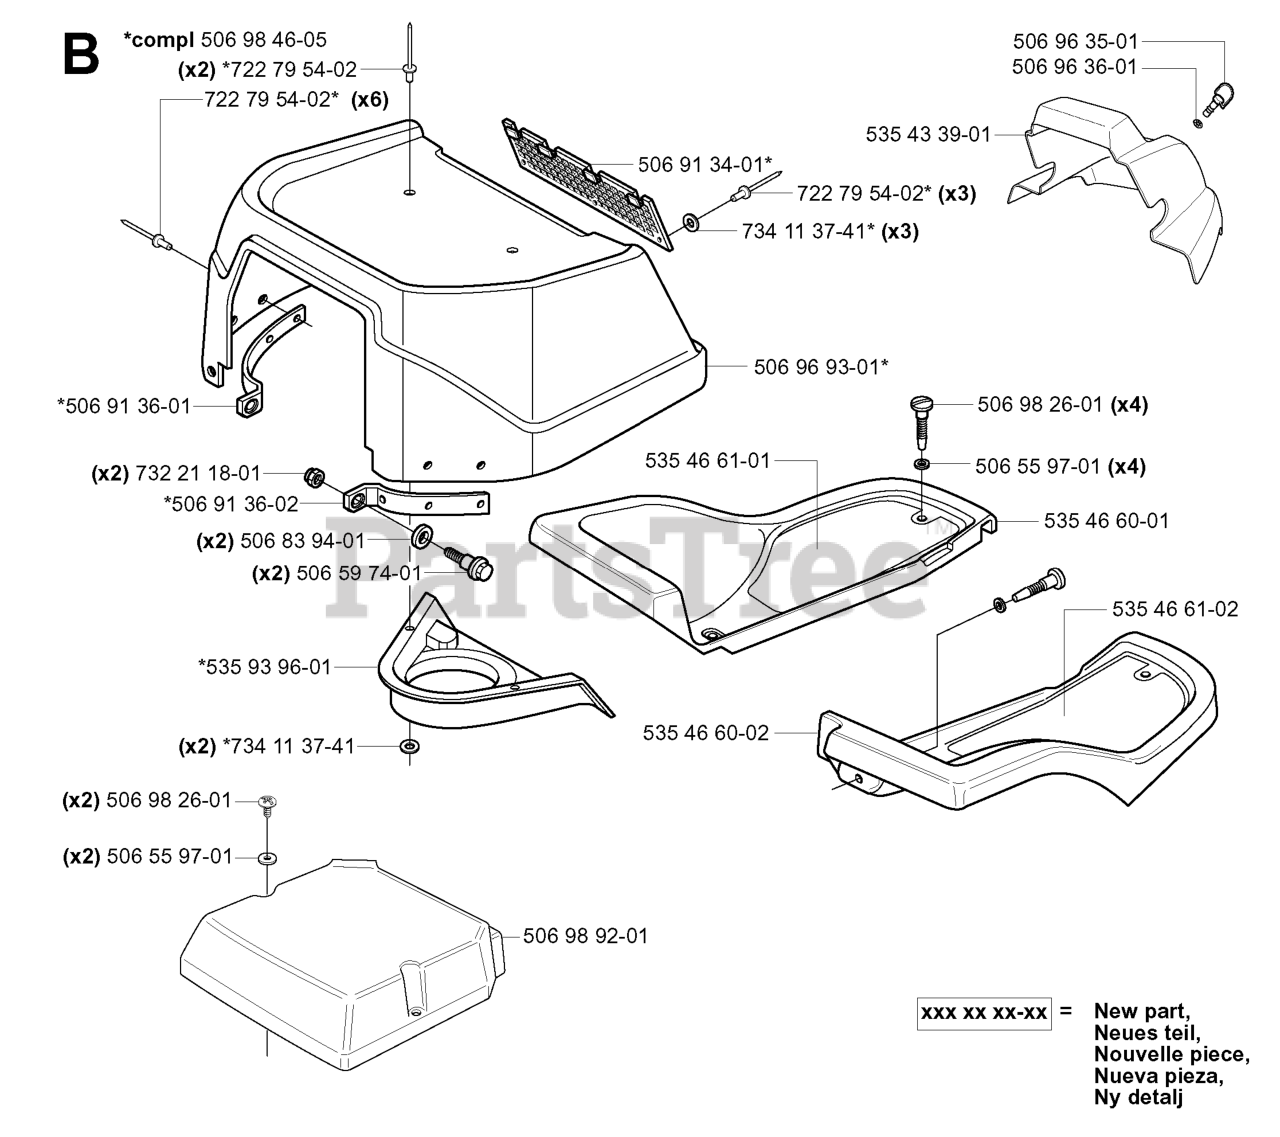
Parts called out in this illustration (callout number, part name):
2	DRAWBAR.STGT
5	DASH.UPR.GT2.SM.PTO.MC.HR.498
14	HOOD.ASM.HUSQVARNA.GT.TEX.ORAN
15	Service Kit
36	SCREW 5/16"
37	FENDER.PNT.TX.GT.CH/FW/DL.HUSQ
58	BRKT.SUPPORT.FNDR/TANK
125	CLIP.FUEL.LINE
137	BUMPER DASH
146	BOLT.RDHD.SHT.SQNK.3/8-16X5/8
150	AIR.DUCT.GTV.BLACK
151	BRACKET.PIVOT.HOOD.GT.HUSQ.II
152	SHIELD.BROWNING.PNT.GT.V2
159	SCREW, 3/8-16X3/4
161	CONSOLE.WINDOW.FUEL.HUSQ.GT
165	SUPPORT.TANK.REAR.B/TE
175	PLATE.PNT.CROSSMEMBER.HUSQ/PRE
176	SCREW.#10-24X5/8.RN.QU
177	BUSHING STEERING
180	CHASSIS.LT/GT.BOLTED
182	DASH.LOWER.COMMON.12V.ADAPTOR
189	SCREW
195	PLUG.HOLE.DASH.LOWER.12V.BLK
196	SUBASM.CONSOLE.HUSQ.GT.DECKLFT
199	PLATE.DECK.LIFT.HUSQVARNA.GT
202	Vents
204	Vents
205	SIDE.TRIM.RH.GT.HUSQ.II
206	SIDE.TRIM.LH.GT.HUSQ.II.GRAY
214	CLIP.RETAINER.TINNER.
217	ROD.PIVOT.HOOD
221	REFLECTOR.LH.TEX GT HU
228	STUD.W/"D"ANTI-ROTATION
236	NUT.CENTERLOCK.5/16-
281	SCREW 3/8-16X1
306	NUT LOCK FLG 3/8-16 UNC
335	COVER.LOWER.DASH.RH.BLACK
336	COVER-LH.LOWER.DASH.GT2.BLACK
350	CLIP.X-MAS.TREE
375	BUMPER CLIP-ON. DASH 1"
378	BUSHING FLANGE; PLASTIC
379	CHASSIS.PLATE.REINFORCEMNT.431
